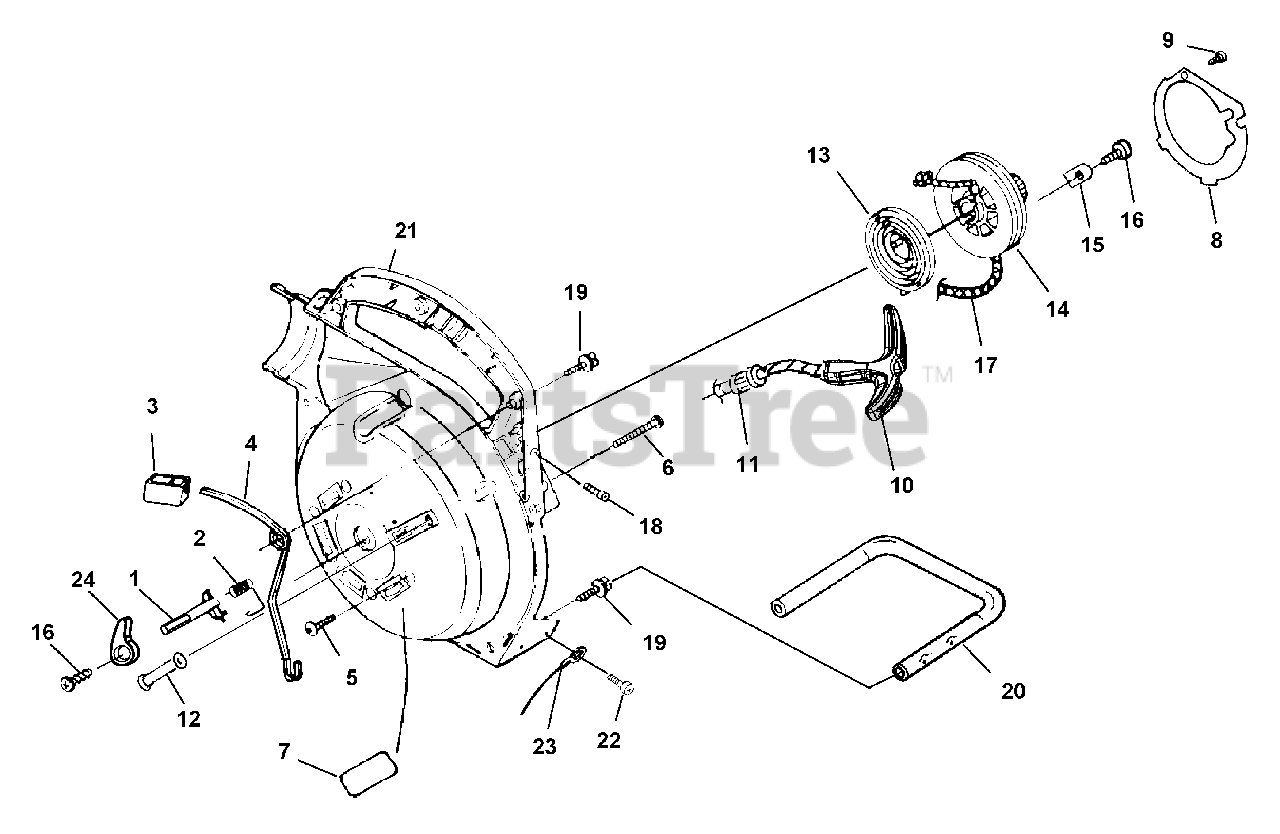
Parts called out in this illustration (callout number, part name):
1	THROTTLE LATCH
2	THROTTLE LATCH SPRING
3	THROTTLE TRIGGER
4	THROTTLE LEVER
5	SCREW (10-24 x 3/4 in.TRUSS HD.)
6	SCREW (10 x 1-5/8 in. HEX HD.)
7	HEAT SHIELD
8	ROTOR PLATE
9	SCREW (#6 x 1 3/8)
10	STARTER GRIP (YELLOW)
11	BUSHING STARTER
12	STARTER ROPE GUIDE
13	SPRING AND CONTAINER
14	STARTER PULLEY
15	RETAINING BRACKET
16	SCREW (10-24 x 1/2 in. TORX TRUSS HD.)
17	STARTER ROPE
18	SCREW (8-32 x 5/8 in. FIL. HD.)
19	SCREW (10-14 x 3/4 in. TORX TRUSS HD.)
21	INNER VOLUTE HOUSING
22	SCREW (8-18 x 1/2 in. PAN HD.)
23	LEAD-GROUND
24	THROTTLE CONTROL KNOB
